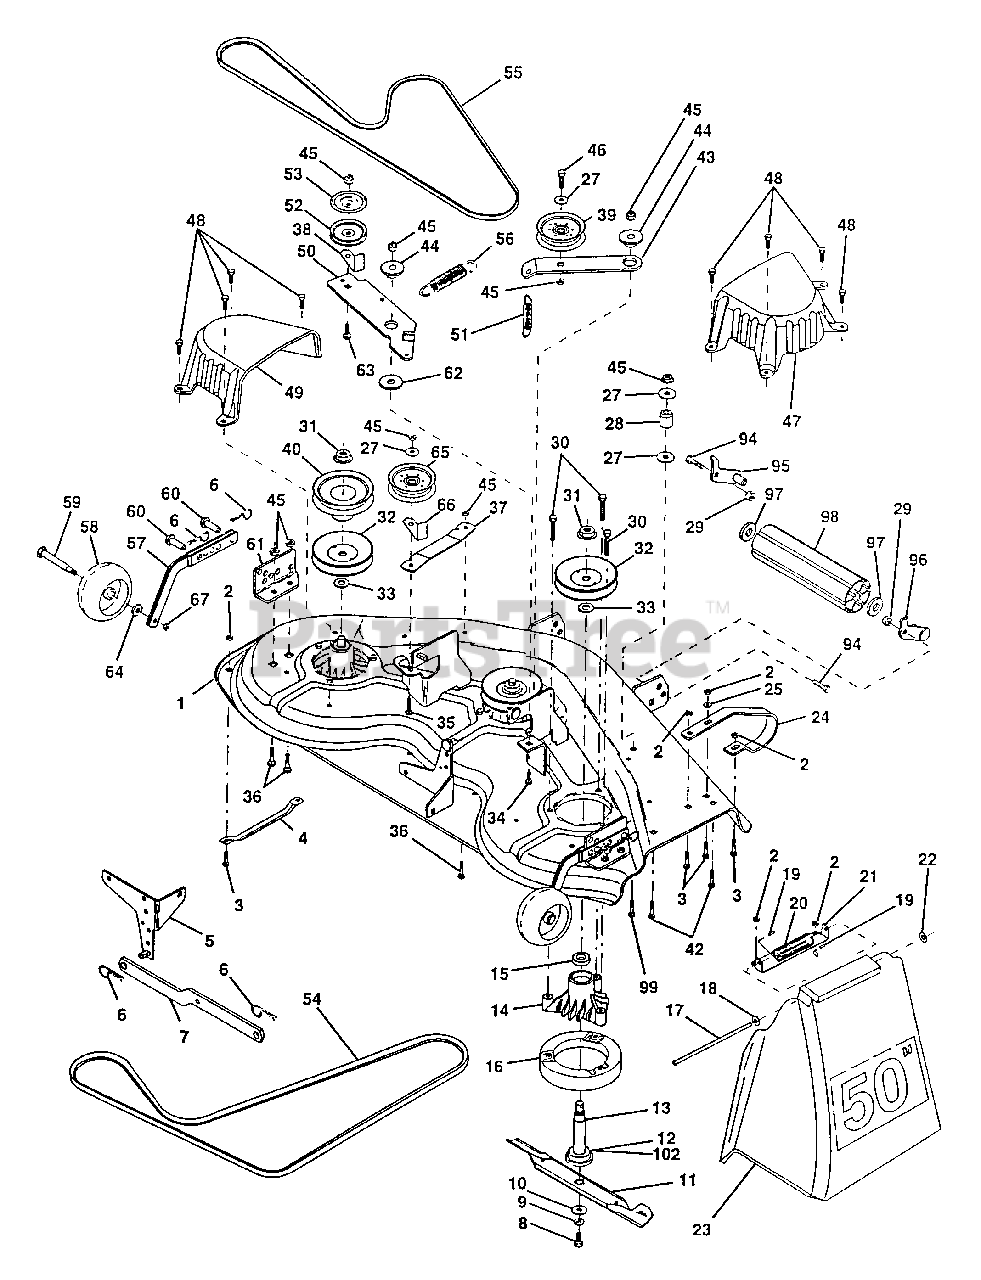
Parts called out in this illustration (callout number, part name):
1	Deck Asm., Mower 50" Vented (AYP part number)
2	Nut, Crownlock 5/16-18
3	Bolt, Carriage 5/16-18 x 3/4
4	Runner, Mower LH
5	Bracket Asm., Sway Bar
6	Retainer, Spring (AYP part number)
7	Arm Suspension, Rear (AYP part number)
8	Bolt 3/8-24 x 1.25 Gr. 8 Patched
9	Washer, Lock Hvy 3/8 Unplated (AYP part number)
10	Washer, Hard Blade Mower Vented
11	Blade
12	Bearing, Ball #6204 (Mandrel)
13	Shaft Asm., W/Lower Brg
14	Housing, Mandrel 50" Vent
15	Bearing, Ball Mandrel
16	Stripper, Mower Vented (AYP part number)
17	Rod, Hinge
18	Washer 11/32 x 5/8 x 16 Ga.
19	Spring, Torsion Deflector
20	Spring, Torison Delector
21	Bracket, Deflector
22	Nut, Push
23	Shield, Deflector Mower
24	Runner, RH
25	Washer 11/32 x 3/4 x 16 Ga.
27	Washer 13/32 x 13/16 x 16 Ga.
28	Spacer, Spring Stop Idler (AYP part number)
29	Nut, Lock Hex W/Wsh 3/8-16 Unc
30	Screw Thdrol Hex Head (AYP part number)
31	Nut, Fig Top Lock Cntr 9/16
32	Pulley, Mandrel (AYP part number)
33	Washer, Spacer Mower Vented (AYP part number)
34	Bolt, Carriage 3/8-16 x 1-1/4
35	Bolt, Carriage 3/8-16 x 2
36	Bolt, Carriage 3/8-16 x 1 Gr. 5
37	Stiffener, Arm Idler
38	Keeper, Belt Idler (AYP part number)
39	Pulley, Idler Flat (AYP part number)
40	Pulley, Driven
42	Bolt, Carriage 5/16-18 Unc x 3/4
43	Arm, Idler Secondary
44	Spacer, Retainer
45	Nut, Crownlock 3/8-16 Unc
46	Bolt, Fin Hex 3/8-16 Unc x 1-3/4
47	Cover, Mandrel RH
48	Screw, Thd Roll 1/4-20 x 5/8
49	Cover, Mandrel LH
50	Arm, Idler Primary
51	Spring, Secondary
52	Pulley, Idler V Groove
53	Shield, Idler
54	V-Belt, Mower Primary
55	V-Belt, Mower Secondary
56	Spring, Primary
57	Bar Asm., Wheel Gauge
58	Wheel, Gauge
59	Bolt, Shoulder
60	Pin, Clevis
61	Bracket, Wheel Gauge
62	Washer Hardened (AYP part number)
63	Bolt Carriage 3/8-16 x 1-1/2
64	Washer 3/8 x 7/8 x 14 Ga.
65	Pulley Idler Flat Mower (AYP part number)
66	Keeper, Belt Idler 50" Vent
67	Nut, Center Lock 3/8-16
94	Bolt H 3/8-16 x 1
95	Bracket, Asm. Noseroller LH (AYP part number)
96	Bracket, Asm. Noseroller RH (AYP part number)
97	Washer 17/32 x 7/8 x 16 Ga.
98	Roller, Nose (AYP part number)
99	Bolt, Carriage 3/8-16 x 1-3/4 Gr. 5
102	Washer Felt
